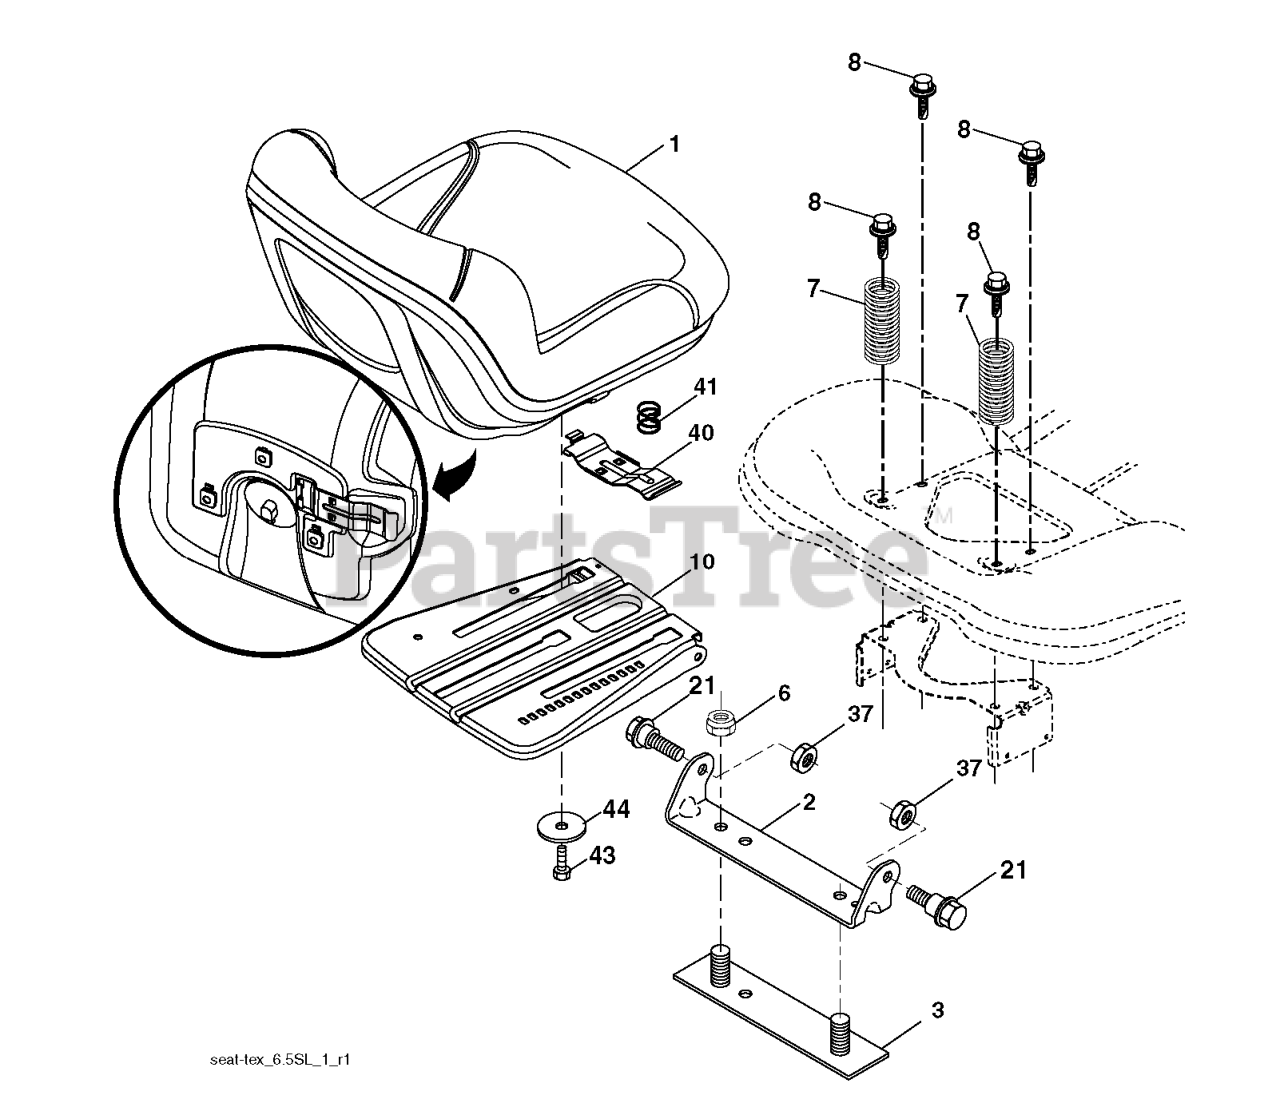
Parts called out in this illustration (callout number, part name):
1	RP SEAT.TH130.GRY.MILSCO.
2	BRKT.PIVOT.FENDER
3	STRAP
6	NUT
7	SPRING COMPRESSION
8	BOLT.5/16-18UNCX3/4 W/SEMS.BLK
10	PAN.ASM.SEAT.3PT
21	BOLT.SHOULDER.5/16-18
37	NUT.71038.31-18.HEX.NYLOCK
40	HANDLE.SLIDE.SEAT.TEX.BLACK
41	SPRING.LATCH.SEAT.TEX
44	WASHER 13/32 X 2-3/8 X 12GA
